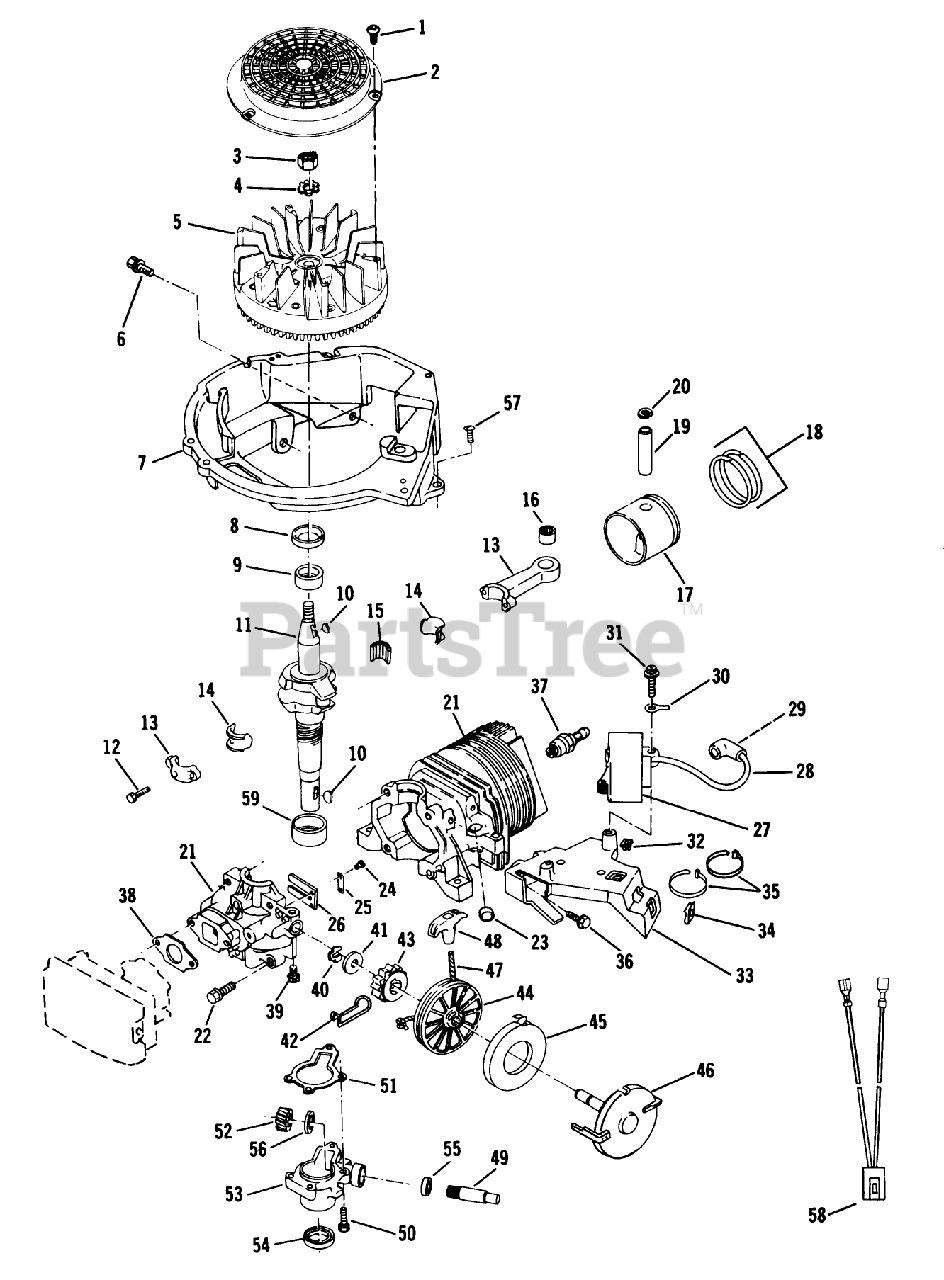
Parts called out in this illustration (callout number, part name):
1	Screw-Flywheel Screen
2	SCREEN F'WHEEL S
3	NUT
6	SCREW-SEMS
9	BEARING V
10	KEY
12	SCREW-HSH
14	LINER ASM
16	BEARING AY F
20	RING-RETAINING
22	SCREW S
23	PLUG-CORE VF
25	PLATE-BACKUP, REED
28	HT LEAD&COVER XEV
30	TERMINAL S
31	6 Screw-C.D. Mounting
32	NUT-CLIP
34	NUT - SPEED S
38	GASKET CARB S
41	WASHER S
44	Pulley
45	SPRING&RET.AY S
46	SPRING CUP&PIN S
48	HANDLE STARTER S
51	GASKET S
52	GEAR, DR SHAFT S
54	SEAL-OIL
55	SEAL S
56	THRUST WASHER
57	SCREW F
59	BEARING S
